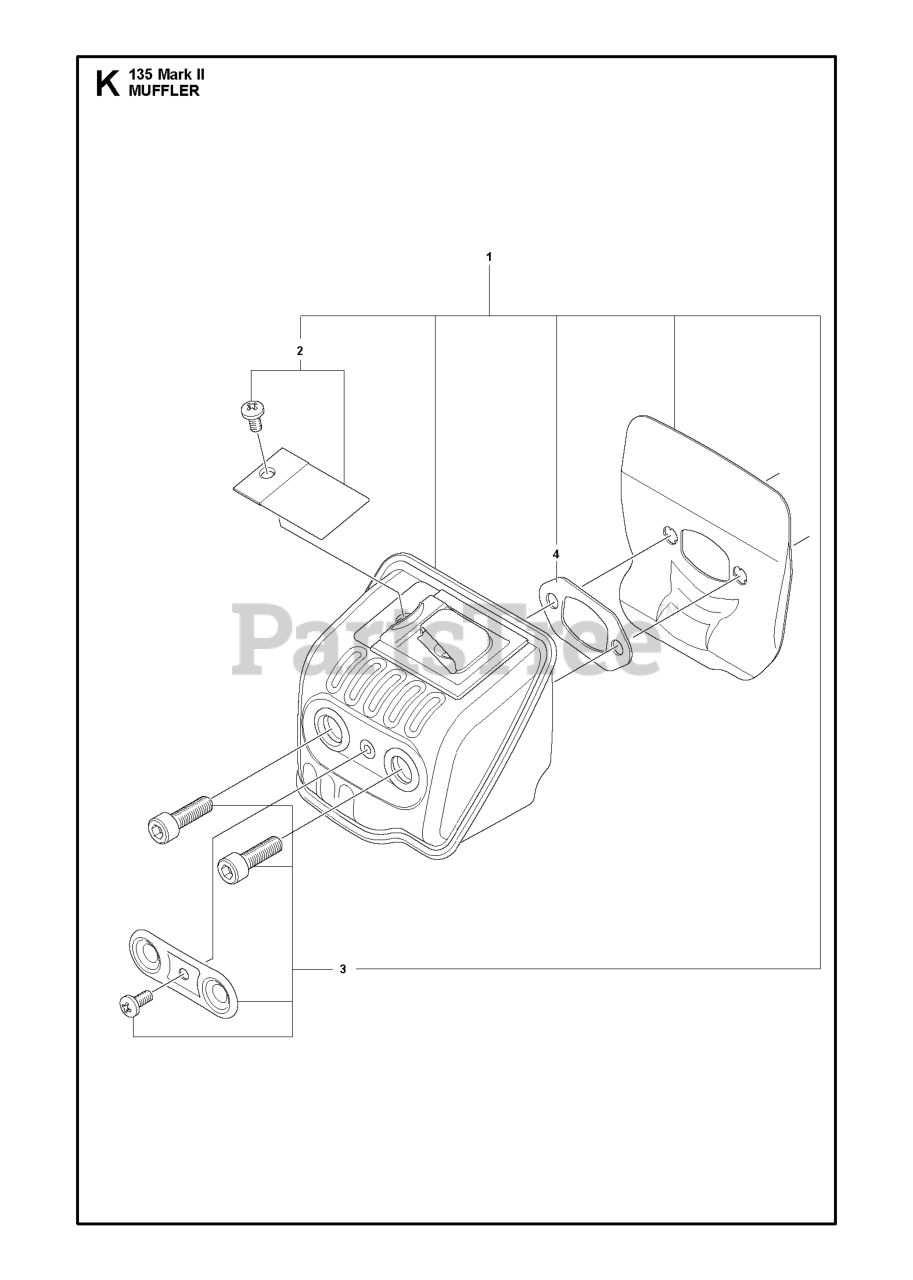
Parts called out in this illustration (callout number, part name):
1	MUFFLER ASSY 38CC
2	SERVICE KIT SPARK ARRESTOR
3	SERVICE KIT MUFFLER
4	GASKET MUFFLER 38CC
